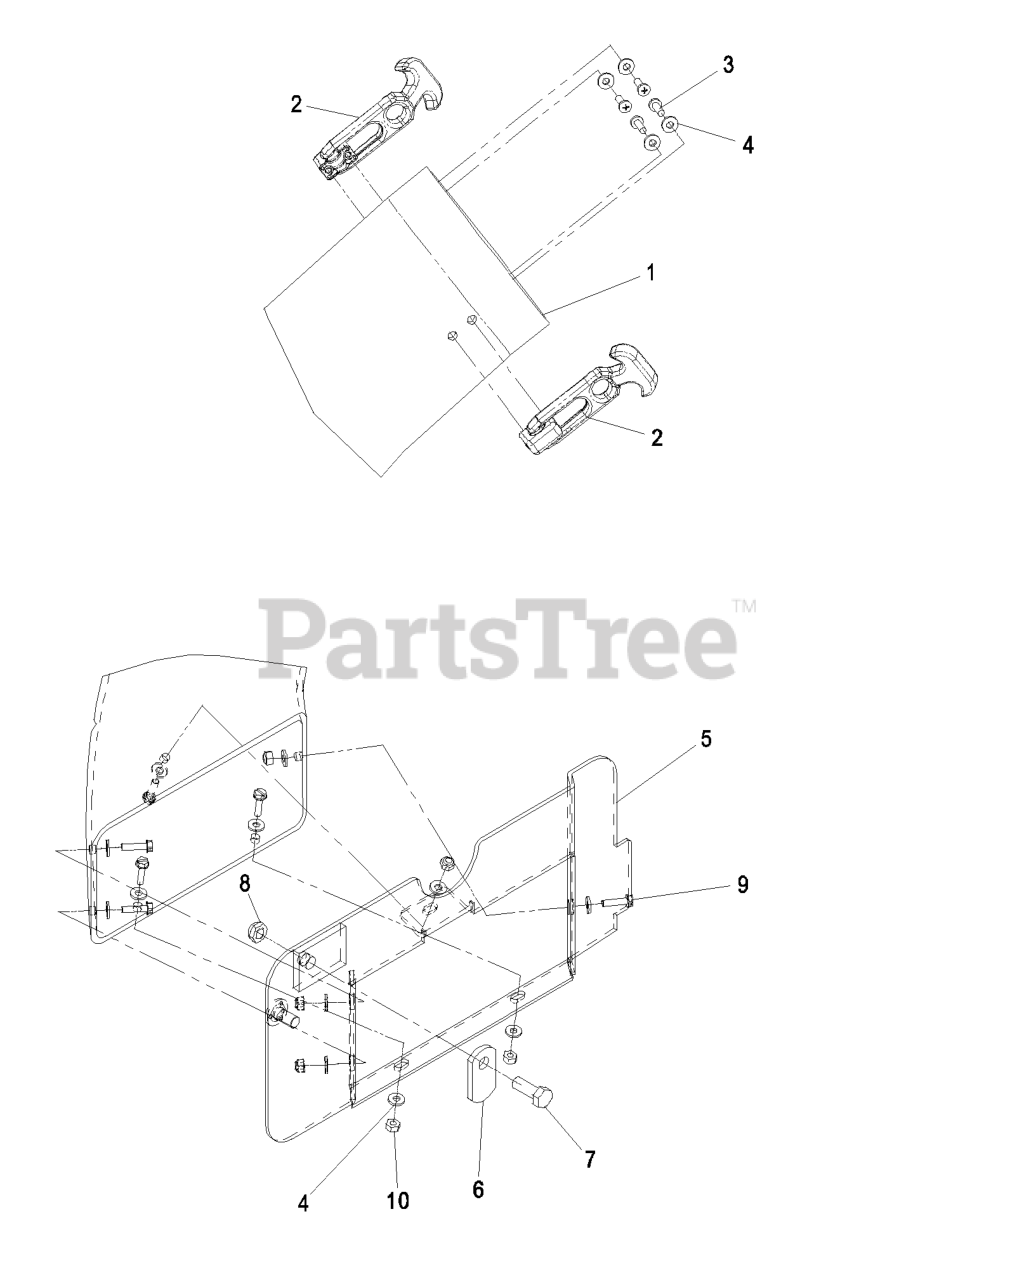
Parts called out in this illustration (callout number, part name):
1	BOOT-LOWER
2	LATCH-RUBBER
3	SCREW-PPH
4	WASHER-FLAT
5	BOOT FRAME ASM
6	LATCH-CATCHER, GRASS
7	SCREW-HH
9	SCREW-HWH
10	NUT-LOCK, NI
